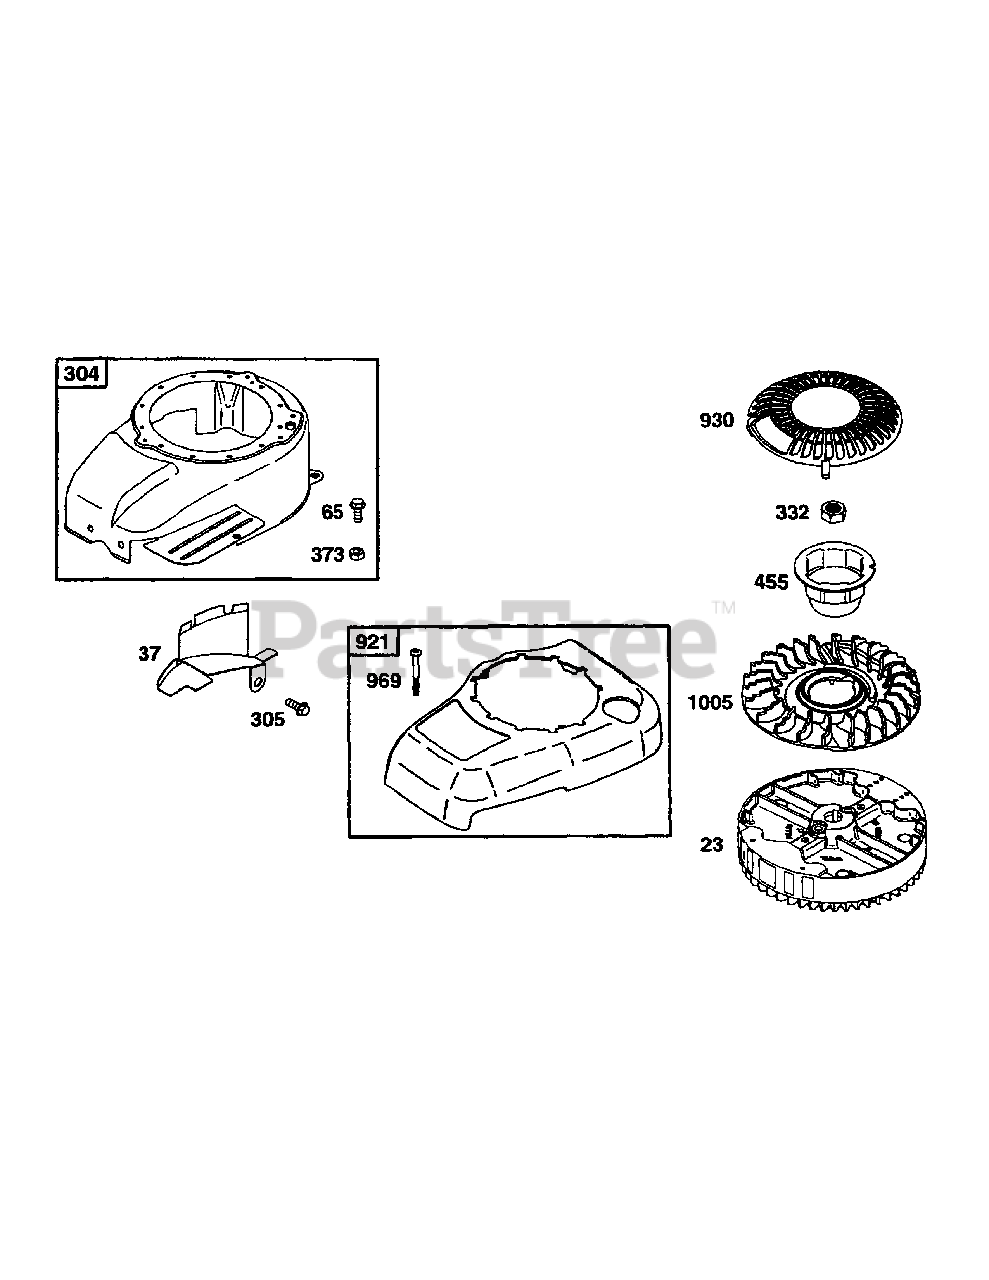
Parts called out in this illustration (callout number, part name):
23	Flywheel
37	Flywheel Guard
65	Hex Screw
304	Blower Housing
305	Hex Screw
332	Flywheel Nut
373	Hex Nut
455	Flywheel Cup
921	Blower Housing Cover
930	Rewind Guard
969	Blower Housing Cover Screw
1005	Flywheel Fan
